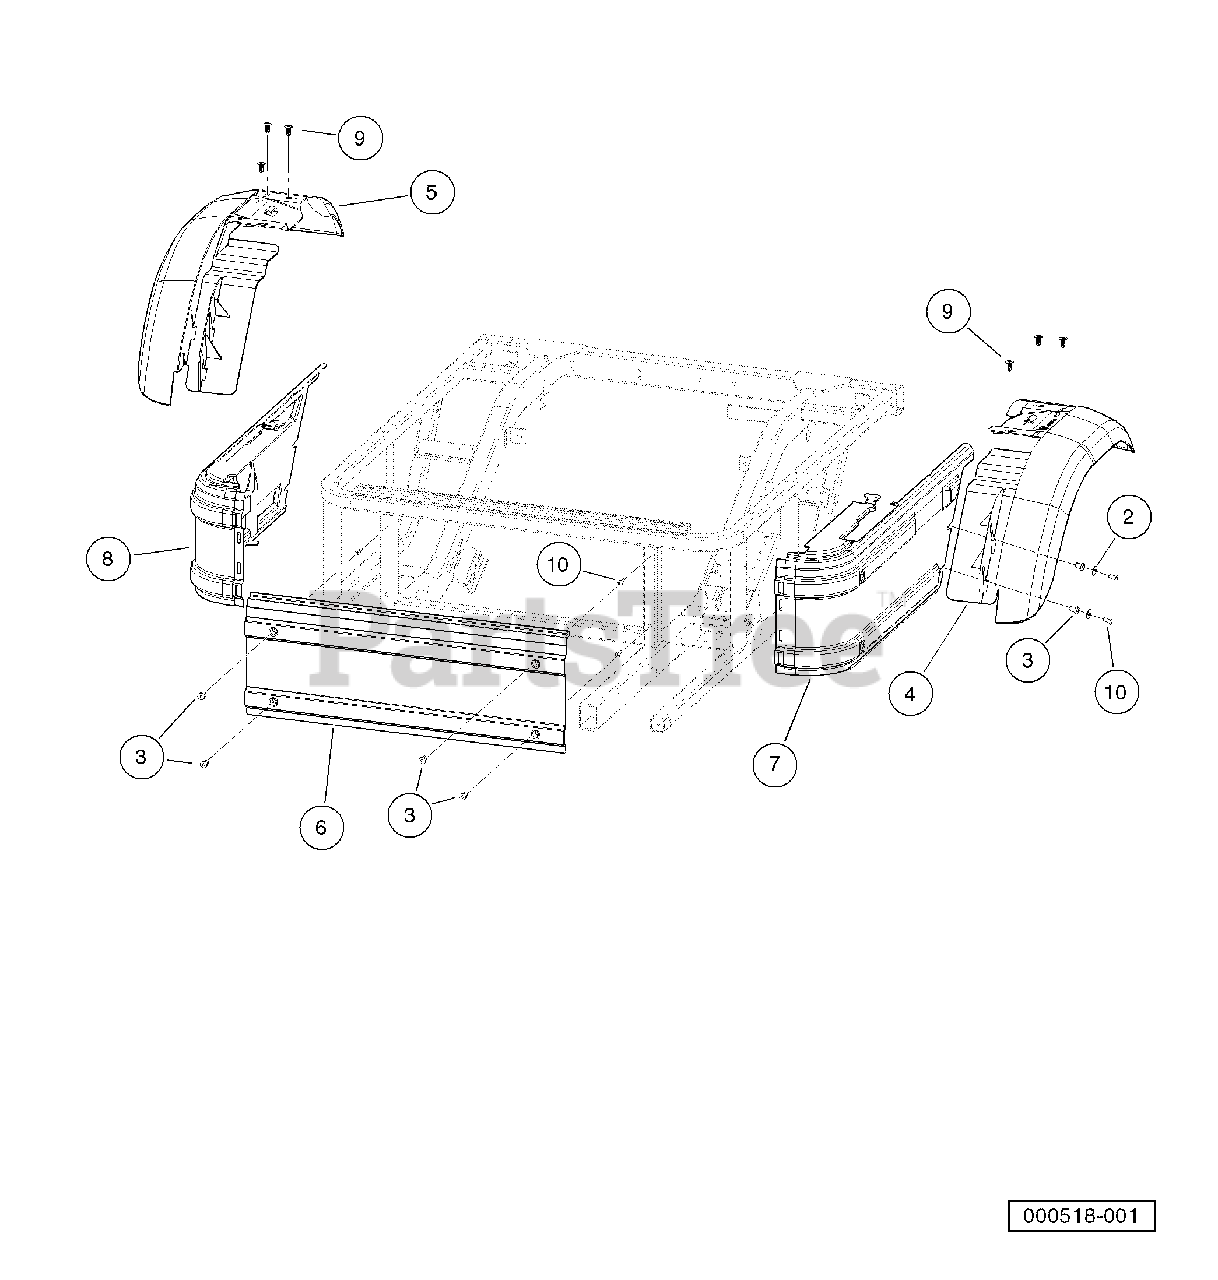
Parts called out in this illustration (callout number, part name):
1	Instl, Panels, Fenders, Blk
2	Washer, 1/4" Type B Flat
3	Well Nut 1/4-20
4	Left Rear Fender
5	Right Rear Fender
6	Panel, Front, Kick
7	Panel, Side, Molded, Driver
8	Panel, Side, Molded, Passenger
9	Screw, Tuflok, 10mm
10	Screw, 1/4-20 X 1.0 Truss-Head Machine
